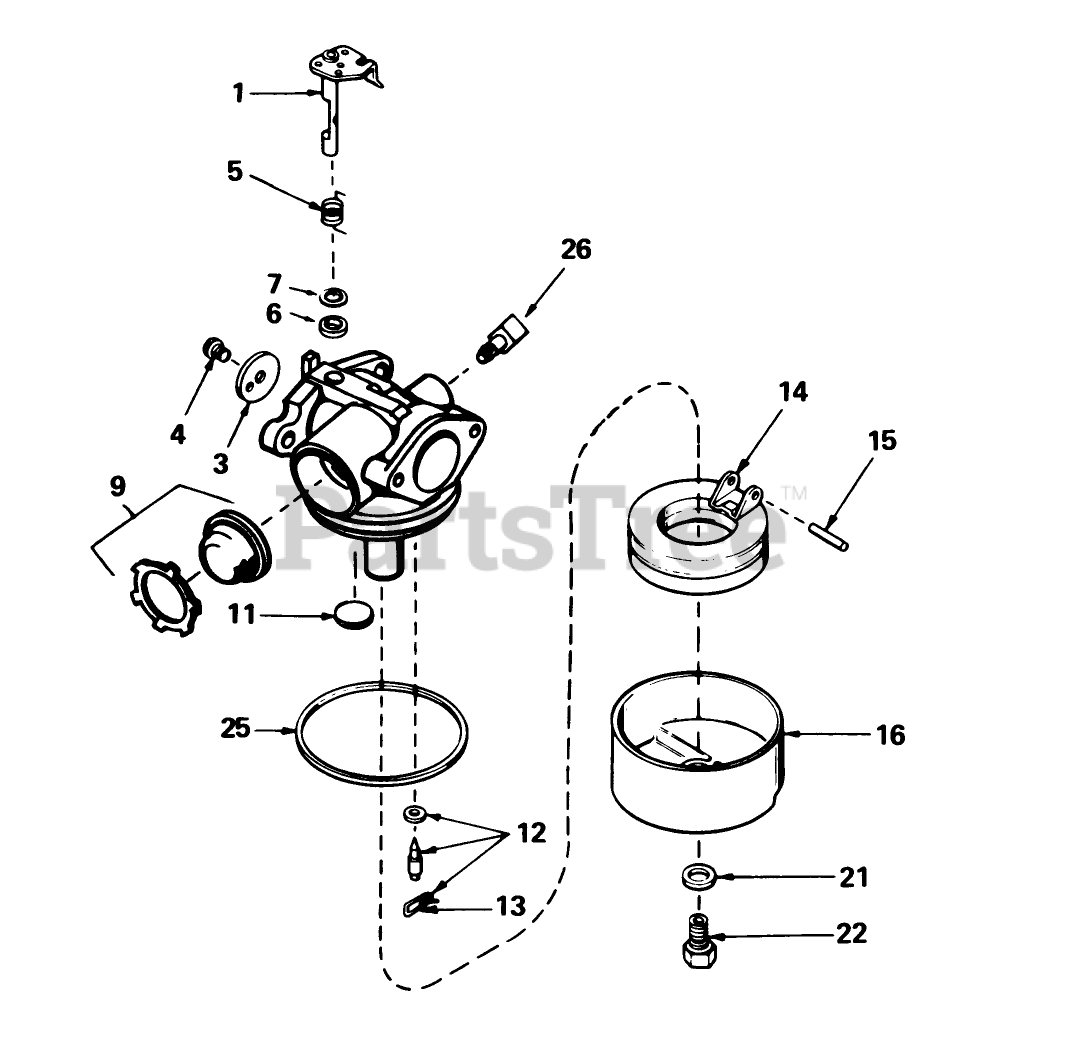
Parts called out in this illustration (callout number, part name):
1	Throttle Shaft and Lever ASM
3	Throttle-Shutter
4	Screw-Shutter
5	Spring-Return, Throttle
6	Seal-Dust
7	Washer-Seal, Dust
9	Primer Assy.
11	Plug-Welch, Atmospheric Vent
12	Inlet Needle, Seat Clip Assy. (Incl. No. 13)
13	Clip-Spring
14	Float
15	Shaft-Float
16	Bowl Float
21	Gasket-Bowl
22	Nut-Float Bowl
25	O Ring-Bowl, Float
26	Fitting-Fuel
